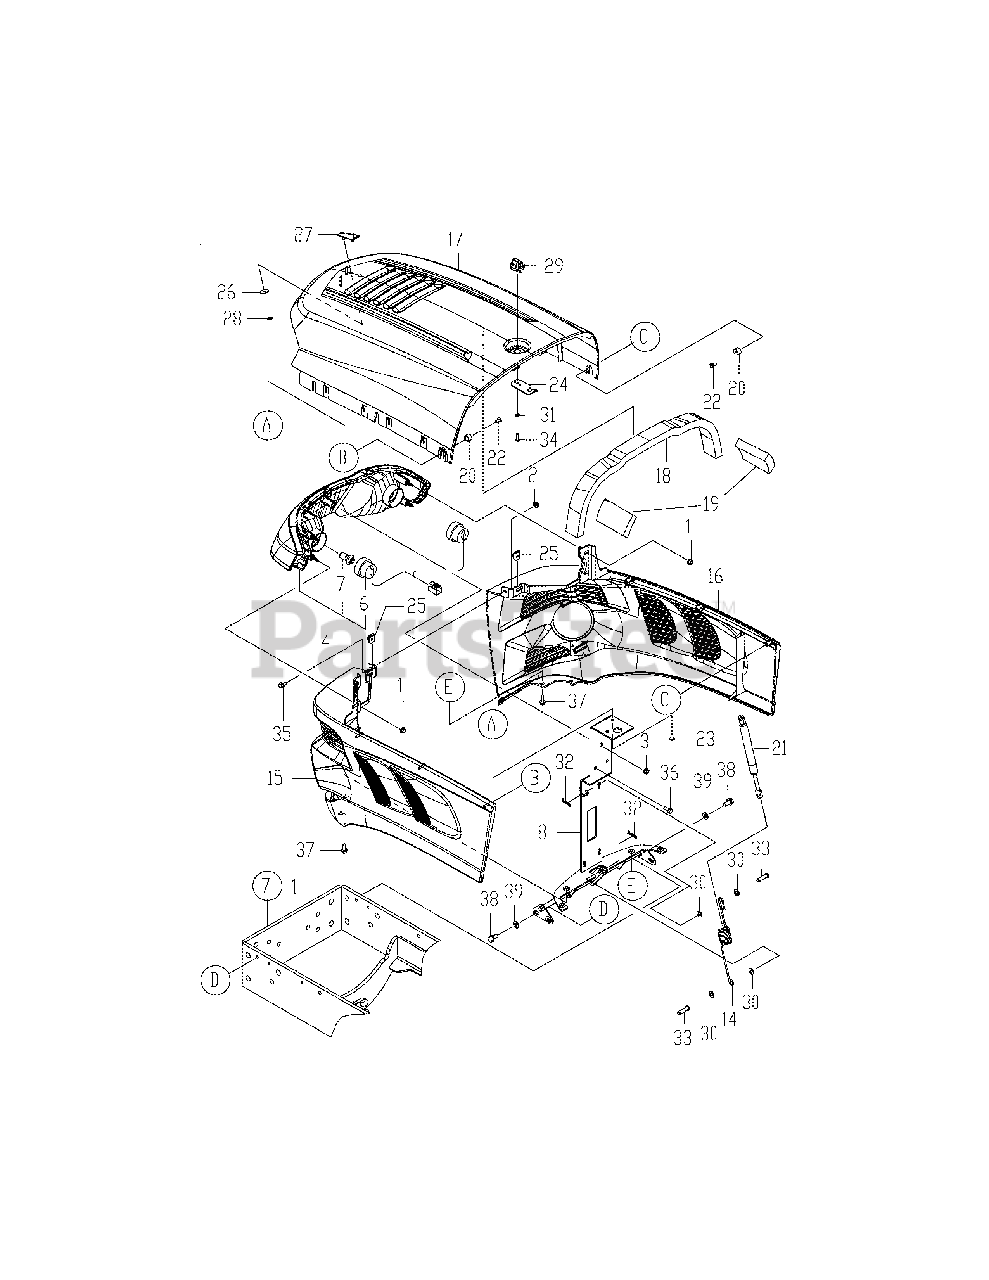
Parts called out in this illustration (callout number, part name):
4	Lamp Assy,Head
6	Wire, Lead Head Lamp
7	Bulb, Halogen12V30/30
8	Hinge Cmp, Hood
14	Spring, Hood Hinge
15	Hood, Lower LH
16	Hood, Lower RH
17	Hood, Upper
18	Seal, Hood Upper
19	Cushion, Hood Rear
20	Collar, 10X15X10
24	Stopper (Hood)
34	Screw, 5.0 X 16
39	Washer 8, Polished
